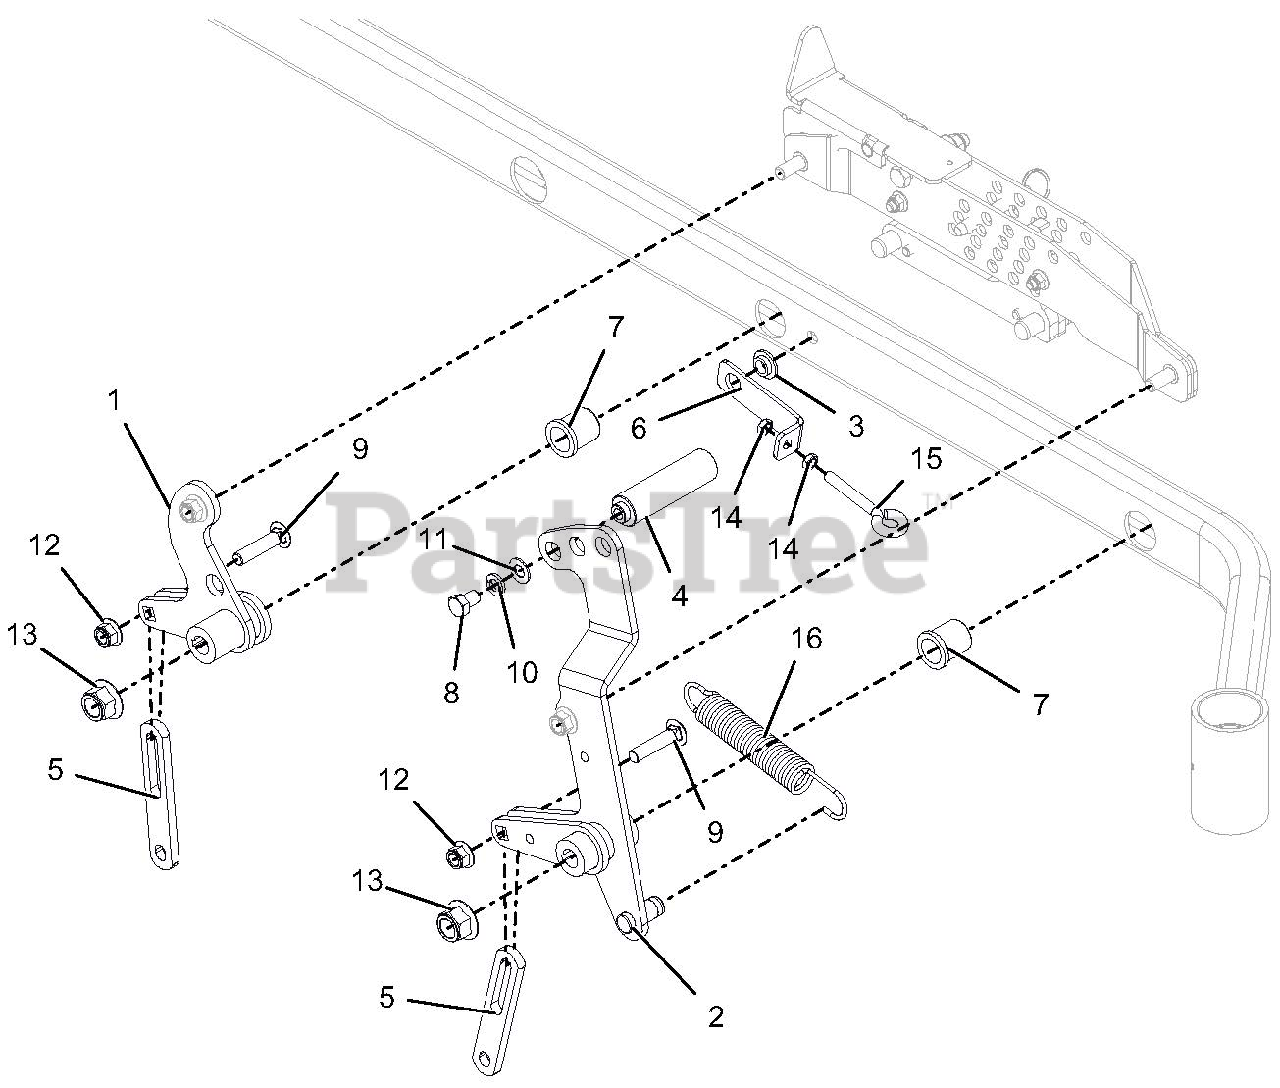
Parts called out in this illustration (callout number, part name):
1	WLDMT, REAR RH DECK LIFT ARM (BLACK)
2	FRT RH DECK LIFT ARM WLDMT-LF
3	BSHG-FLG .515X.750X.310X1.120
4	FOOT PEG, DECK LIFT
5	LINK-DECK LIFT - LONG
6	SPRING ANCHOR BRACKET - RED
7	BSHG-FLG 1.00X1.25X1.50X1.50
8	@BLT-HEX .50-13X.75 GR5 YWZC
9	BLT-RDHDSQNK .50-13X2.25 G5YZ
10	@WSHR-LK .50X.125 REG YWZC
11	WSHR-FL-STL .505X1.00X.062YWZC
12	@NUT-LK-NYL-FLG .50-13 YWZC
13	@NUT-LK-NYL-FLG .75-10 YWZC
14	NUT-HEX-JAM .375-16 YWZC
15	BLT-EYE .375-16X2.50 YWZC
16	SG-TENS .162X1.25X8.25 WLD 25
